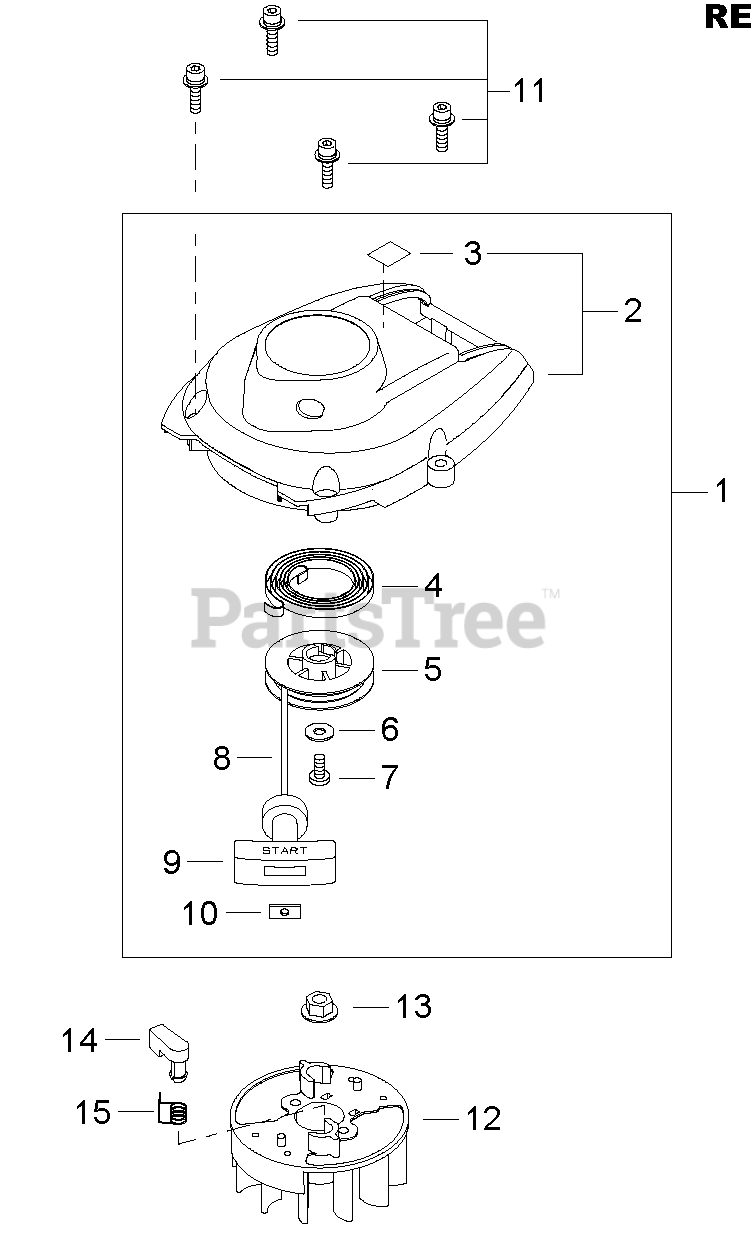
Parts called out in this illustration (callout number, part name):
1	STARTER ASSY, RECOIL
2	CASE ASSY, RECOIL STARTER
3	LABEL, CAUTION - HOT
4	SPRING, RECOIL
5	REEL, ROPE
6	WASHER 5
7	SCREW 5
8	ROPE, STARTER
9	GRIP, STARTER
10	RETAINER, ROPE
11	BOLT, ADHESIVE M5×20
12	FLYWHEEL
15	SPRING, TORSION
